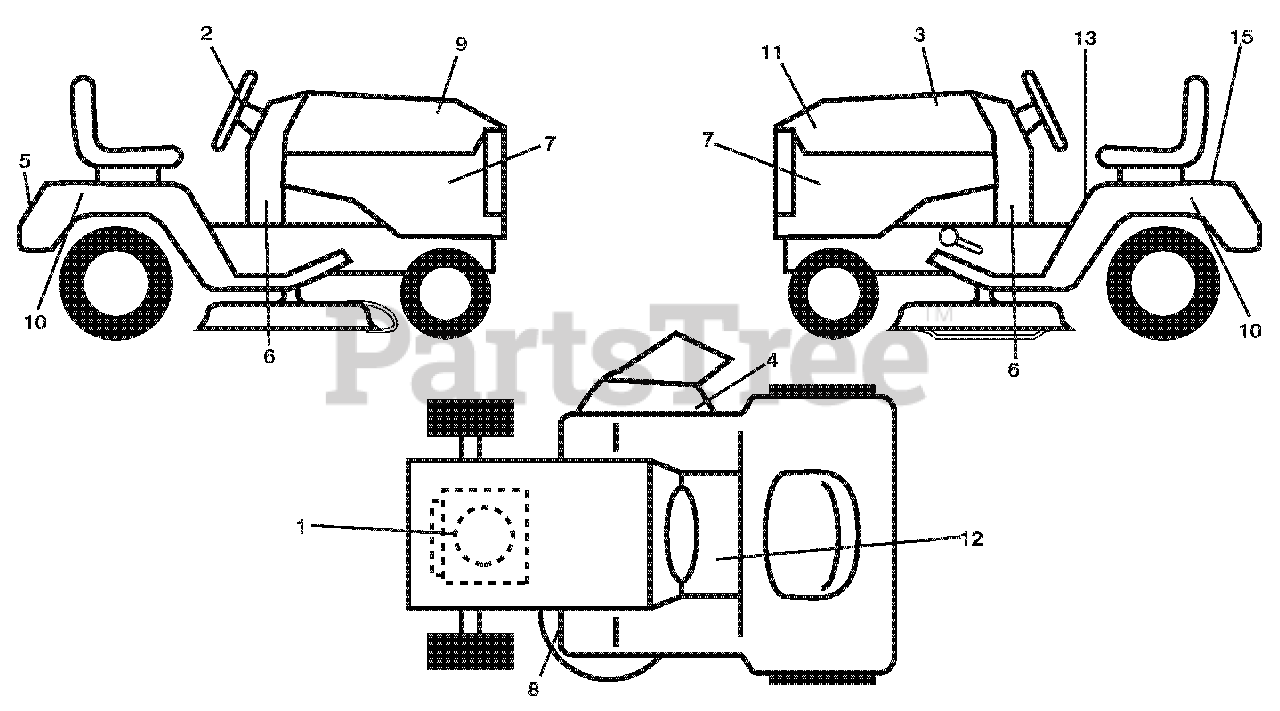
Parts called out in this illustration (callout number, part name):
1	DECAL, REPLACEMENT
2	Decal, Ins Str Wh
3	DECAL.REPLACEMENT
4	DECAL.WARNING.KEEP.HAND.AWY
5	DECAL.FENDER.REAR.ARIENS
6	DECAL, DASH LOWER
7	DECAL.SDPNL.PWRDBY B&S.ARIENS
8	DECAL.V-BELT.SCH.
9	DECAL.HOOD.RH
10	DECAL.FENDER.SD.GEAR.DR
11	DECAL.HOOD.LH
12	DECAL.FENDER
13	DECAL.WARNING.START
15	DECAL.BAT.DAN/POI P/L SYM.WPN
